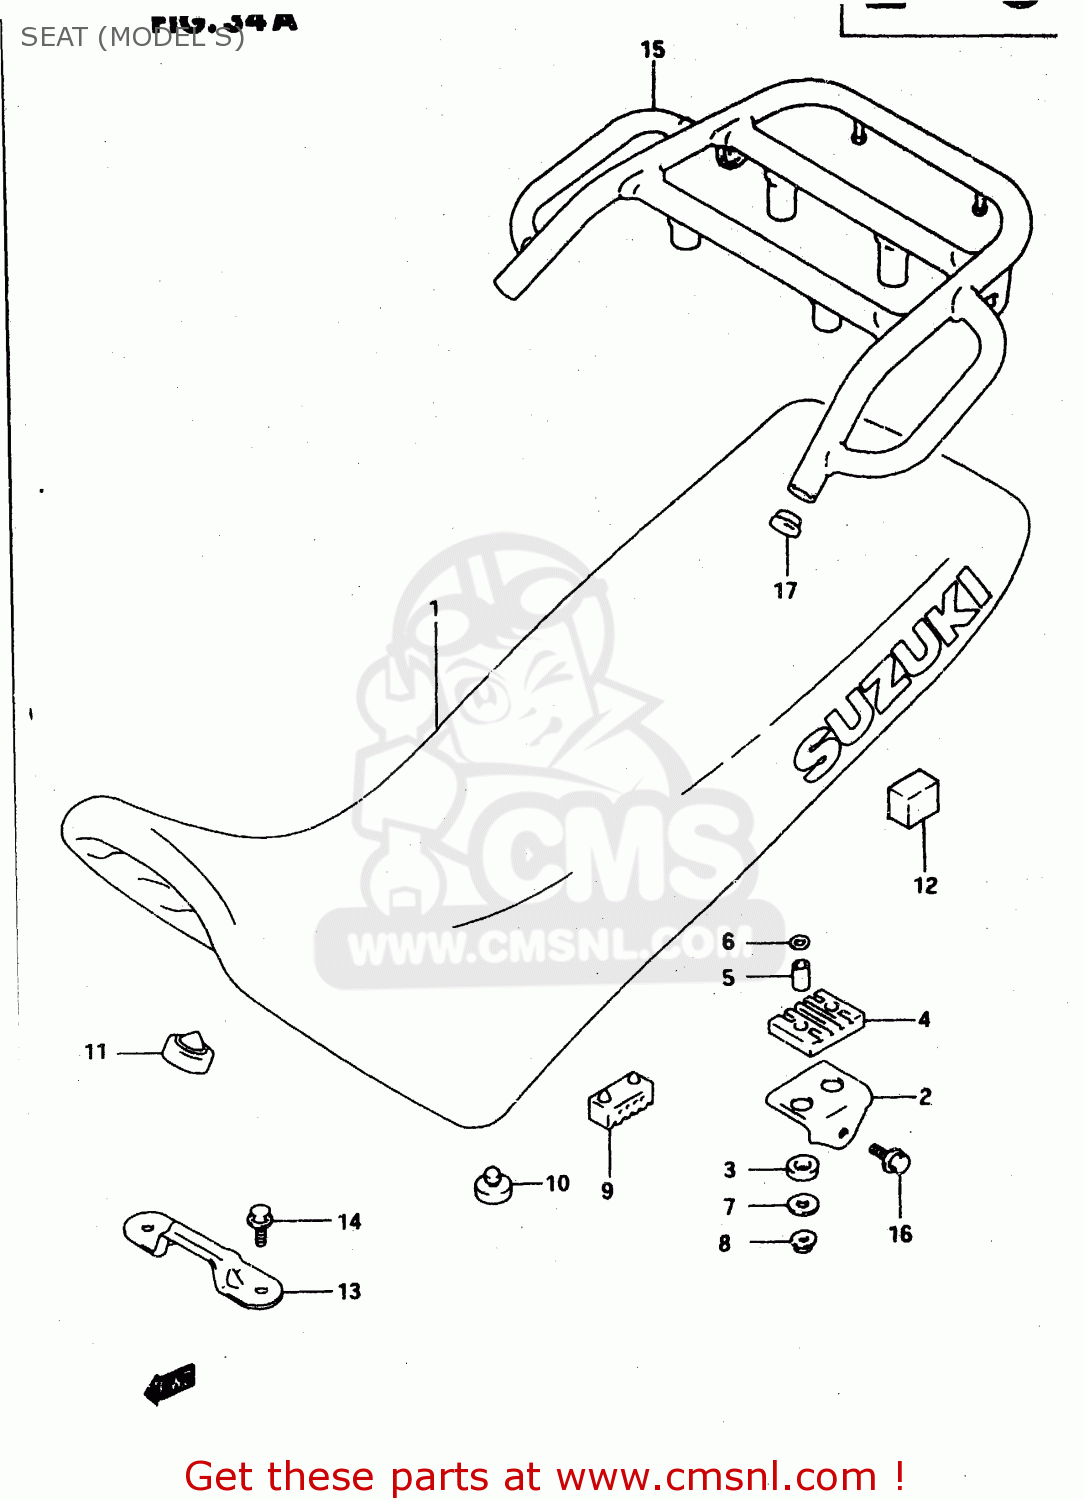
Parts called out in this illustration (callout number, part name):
1	SEAT SET
2	BRACKET,SEAT
3	CUSHION,SEAT FR
4	CUSHION,FR PLATE
5	SPACER,SEAT BRACKET
6	WASHER
7	WASHER
8	NUT
9	CUSHION,SEAT(40X20X15)
10	CUSHION
11	CUSHION,FRONT
12	CUSHION,TOOL(40X30X15)
13	PLATE,SEAT FR HOOK
14	BOLT
15	CARRIER,SPORT
16	BOLT
17	CAP(OD:19)
